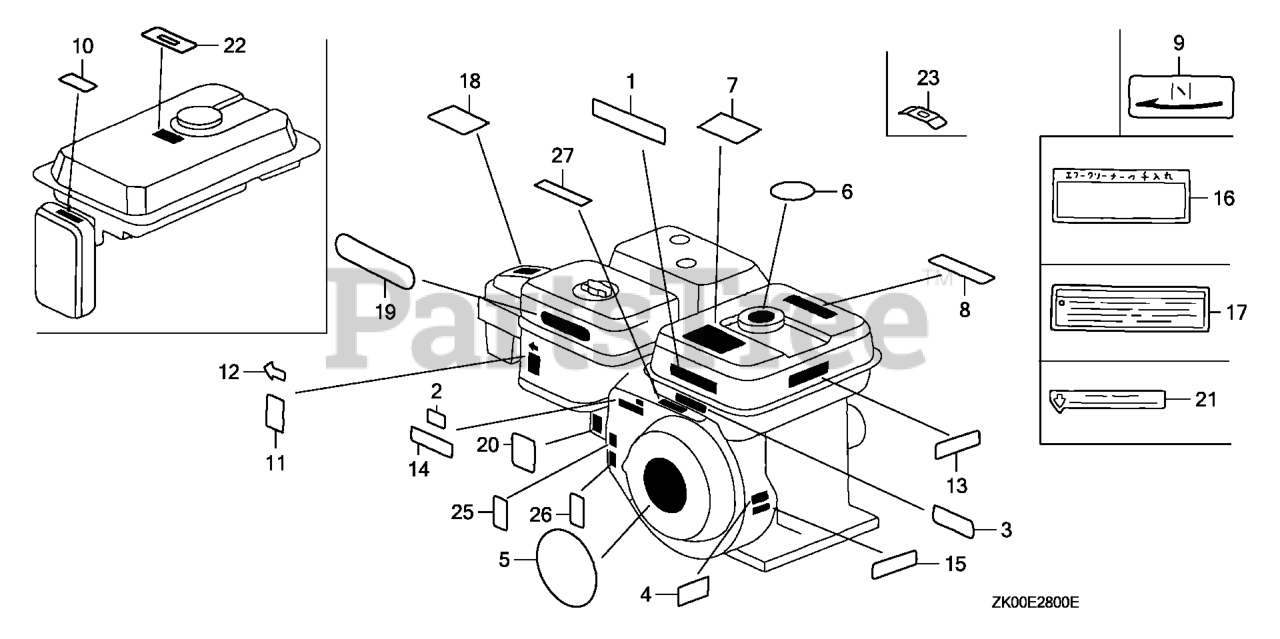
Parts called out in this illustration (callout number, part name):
1	LABEL, CAUTION (ENGLISH, ETC.)
3	LABEL (E-SPEC)
5	EMBLEM (GX200)
11	MARK, CHOKE
13	MARK, OIL ALERT (ENGLISH)
26	LABEL, WARNING (NOT CERTIFIED FOR SALE)
